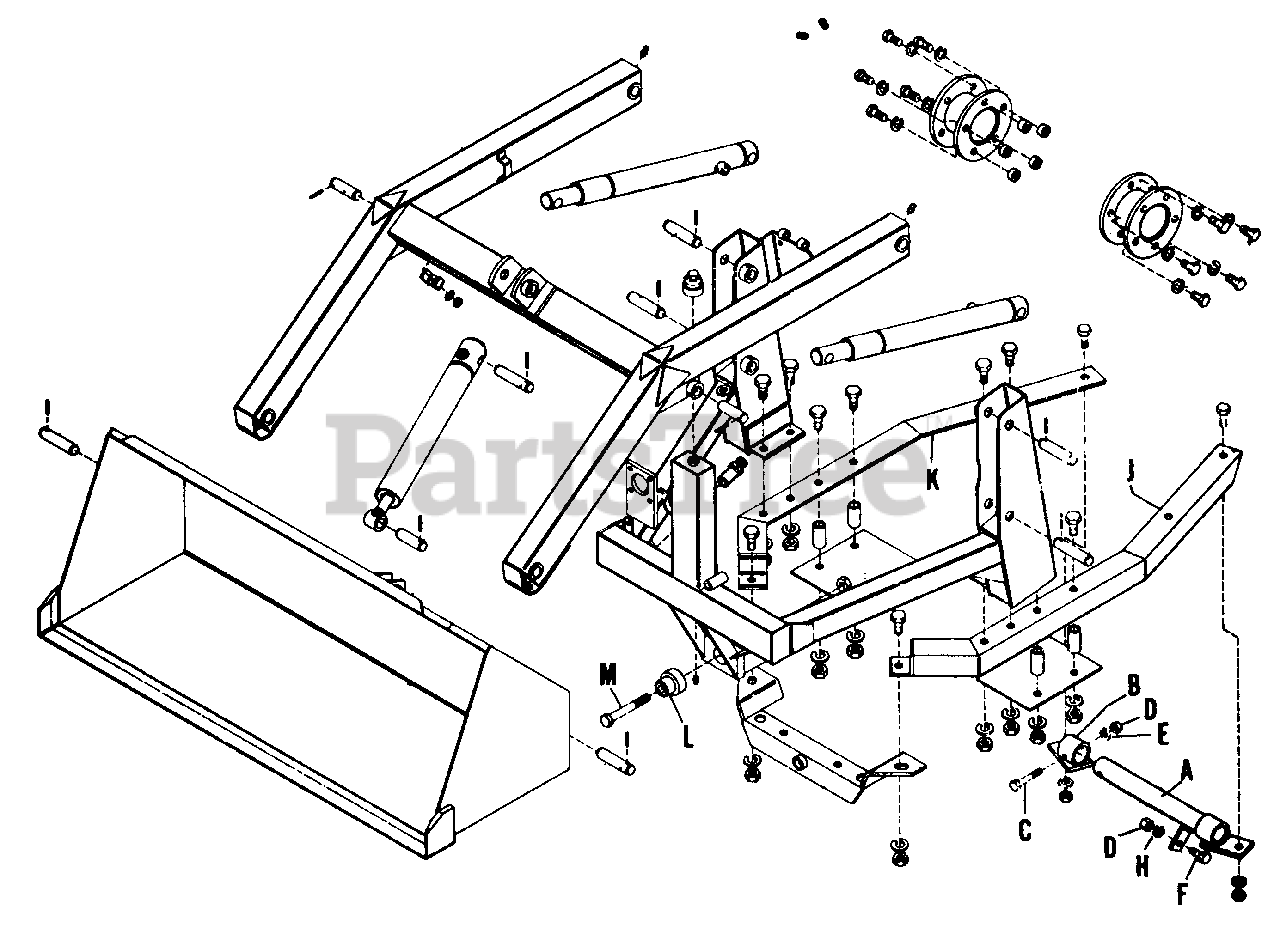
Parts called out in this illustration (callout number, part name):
A	Cross Mount Henry #2019805
B	Right Mount Henry #2019803
C	Screw-Cap-Hex. 3/8"-16 N.C. x 2-1/2" lg. Henry #919363
D	Nut-Hex.-Full 3/8"-16 N.C. Henry #916950
E	Lockwasher 3/8" Henry #916965
F	Screw-Cap-Hex. 7/16"-14 N.C. x 1" lg. Henry #918212
G	Nut-Hex.-Full 7/16"-14 N.C. Henry #918213
H	Lockwasher 7/16" Henry #918199
J	Sub-Frame-Right Henry #2019806
K	Sub-Frame-Left Henry #2019807
L	Front Mount Henry #2019804
M	Screw-Cap-Hex. 1/2"-20 N.F. x 5" lg. Henry #916428
N	"V"-Belt Henry #2019808
P	Spring Henry #2019405
